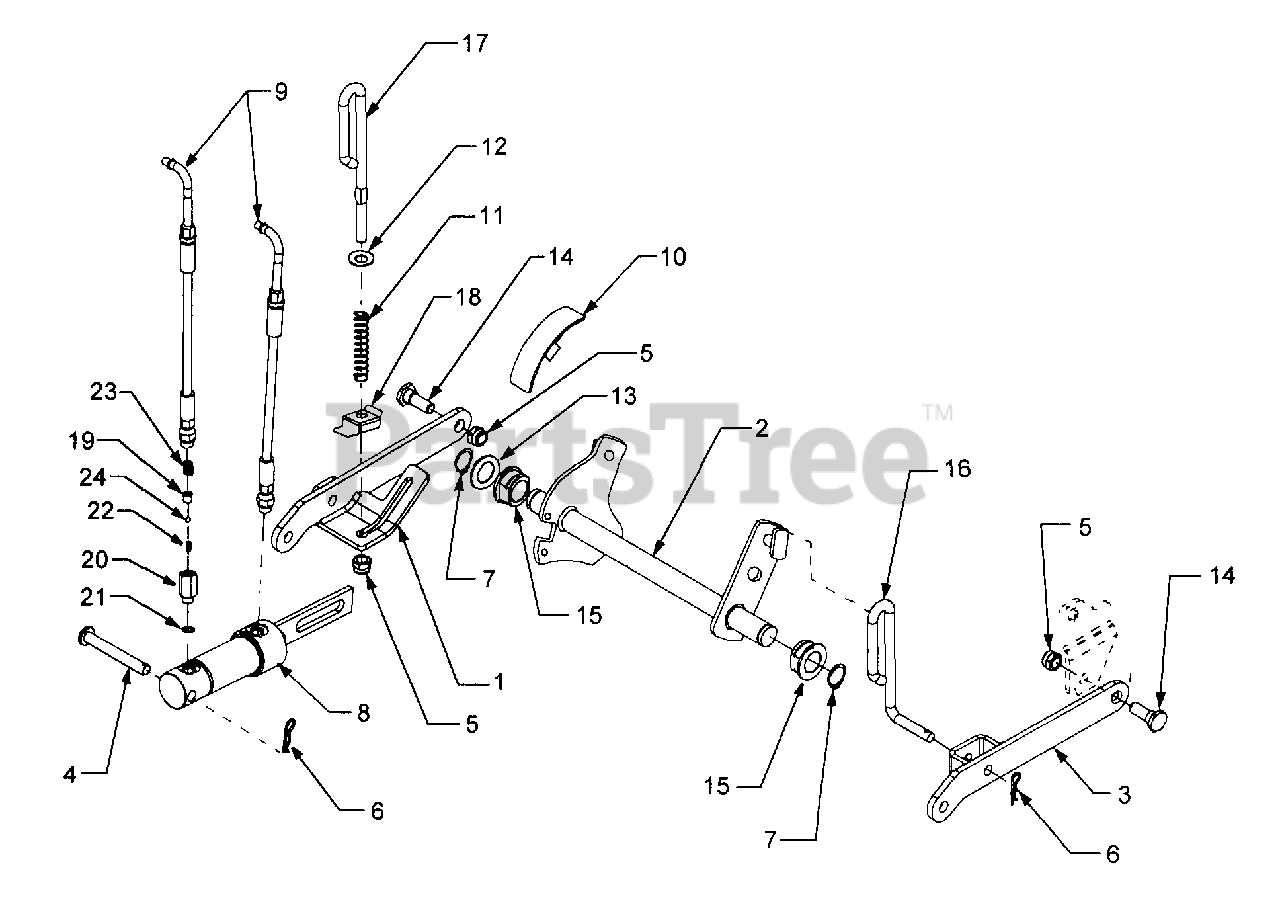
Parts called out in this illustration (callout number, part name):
1	Link, LH Lift
2	Shaft Assembly, Lift
3	Link, RH Lift
4	Pin, Clevis, .5 x 3.75
5	Nut, Hex Lock, 1/2-13
6	Pin, Internal Cotter
7	Snap Ring, 1.0 Dia. Shaft
8	Cylinder, Center Lift
9	Hose, Lift
10	Indicator, Lift Position
11	Spring, Compression
12	Washer, Flat, .536 x .93 x .050
13	Washer. Flat, 1.0 x 1.7 x .10
14	Shoulder Screw
15	Bearing, Flange w/Flats
16	Rod, RH Lift
17	Rod, LH Lift
18	Stop Bracket, Lift Rod
19	Body, Center Check Valve
20	Housing, Check Valve
21	O-Ring
22	Spring, Compression
23	Spring, Compression
24	Ball, Detent
